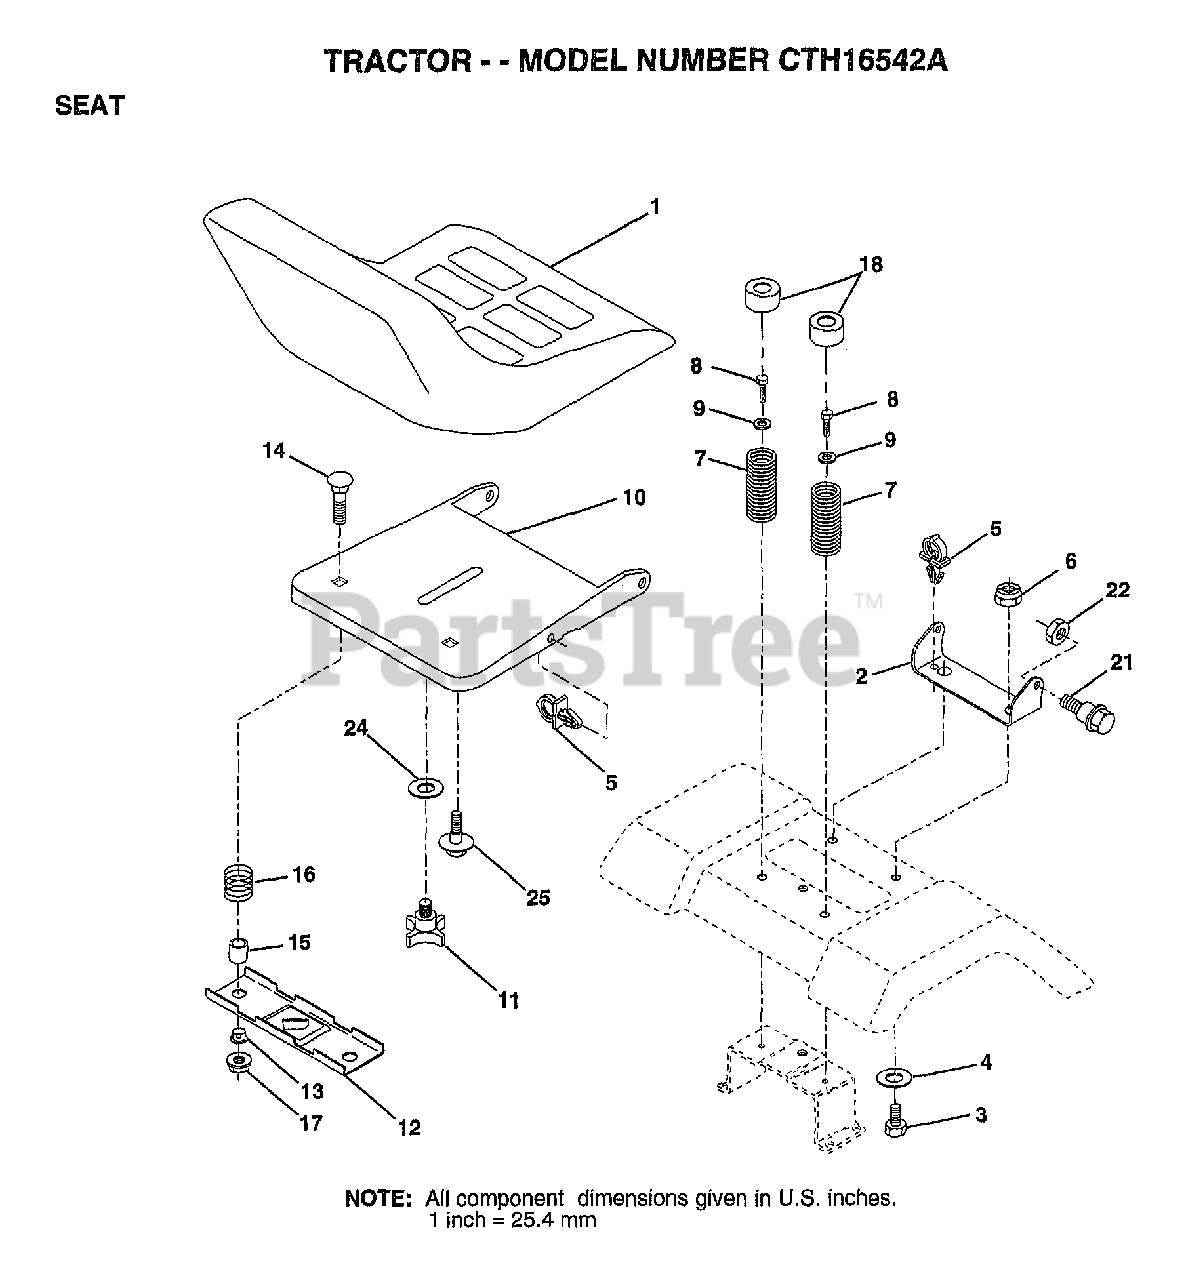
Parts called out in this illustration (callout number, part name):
2	BRACKET PVT SEAT
3	BOLT
4	WASHER PM
5	CLIP.PUSH-IN.HING
6	NUT
7	SPRING COMPRESSIO
8	SCREW GTV
9	WASHER
10	PAN-SEAT
11	"KNOB 1/2"" YT"
12	BRKT SWITCH
13	BUSHING
14	BOLT-RD HD SQ NK
15	SPACER SPLIT
16	SPRING COMPRESSED
18	CAP SPRING
21	"BOLT,SHOULDER"
24	WASHER
25	"BOLT,SHOULDER"
